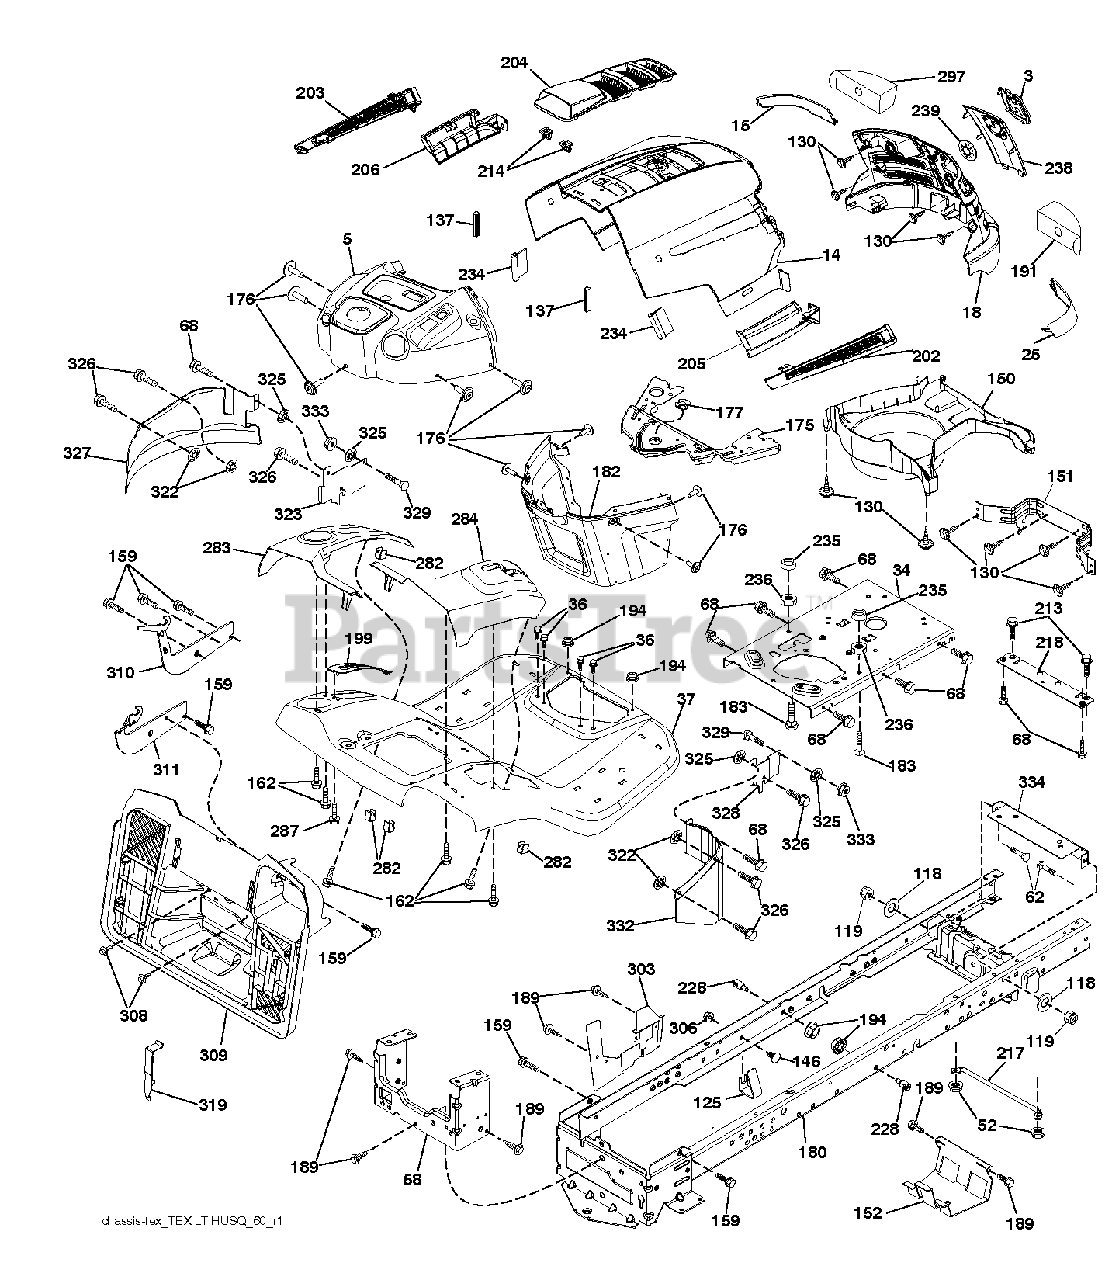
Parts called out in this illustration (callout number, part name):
3	LOGO.HUSQ.GT.LT.CROWN.H
5	SUBASM.DASH.UPPER.W/BUMPER
14	HOOD.HUSQVARNA.LT.ORANGE
15	LENS.HUSQVARNA LT.RH
18	GRILLE.SVC.HUSQVARNA.GREY
25	LENS.HUSQVARNA LT.RH
34	PLATE.ENGINE.10GA.CRD.GENII
36	SCREW 5/16"
52	LOCKNUT
58	DRAWBAR UPPER 2PC SMALL FENDER
62	BOLT D
68	SCREW LT
118	WASHER
125	CLIP.FUEL.LINE
130	SCREW.#10 X 0.750.BOS
137	BUMPER DASH
146	BOLT.RDHD.SHT.SQNK.3/8-16X5/8
151	BRACKET PIVOT
152	SHIELD.BROWNING.W/TEX
159	SCREW, 3/8-16X3/4
162	SCREW.HI-LO.CONSOLE
175	CROSSMEMBER
176	SCREW.#10-24X5/8.RN.QU
177	BUSHING STEERING
180	CHASSIS.WLDMNT.14GA.2PC.18".TI
182	DASH.LOWER.PREDATOR LT
183	BOLT.5/16-18X1-1/4 FULL THD
189	SCREW
191	INSERT.REFLECTIVE.RH.
194	NUT LOCK HEX FLANGE 5/16-18
199	PLATE DECK LIFT
202	VENT.SIDE.HUSQVARNA.LT.RT
203	VENT.SIDE.HUSQVARNA.LT.LFT
204	SUBASM.TOP.VENT.HUSQ.LT
205	SKIRT.SIDE.HUSQVARNA.LT.RT
206	SKIRT.SIDE.HUSQVARNA.LT.LEFT
213	BOLT
214	CLIP.RETAINER.TINNER.
217	ROD.PIVOT.HOOD
218	X-PIECE.HOOD.STOP.NON/
228	STUD.FASTNER.W/ANTI-ROTATE
234	BUMPER.HOOD.TEX.HUSQVARNA
235	SPACER FENDER
236	NUT.CENTERLOCK.5/16-
238	TRIM.HUSQ LT.668
282	CLIP.RETAINER.CONSOLE.LT.HUSQ
283	CONSL.DECKLIFT.LH.SRD.TEX.CRD
284	CONSL.SHIFT.GEAR.RH.SRD.GREY
287	SCREW 1/4X20
297	INSERT REFLECTIVE
303	SHIELD CHASSIS LEFT
306	NUT LOCK FLG 3/8-16 UNC
308	BOLT, 5/16-18 X 1 3/4
309	BACKPLATE.BAGGER.V2.SRD
310	LH.ADJUST.HANGER.BRACKET.ASM
311	RH.ADJUST.HANGER.BRACKET.ASM
319	BRACKET.ACTUATOR.BAGGER.SRD
322	PALNUT 1/4
323	GUARD FRONT LEFT
325	WASHER 5/16"
326	SCREW 14-20 X 5/8
327	GUARD LEFT
328	GUARD FRONT RIGHT
329	BOLT
332	GUARD RIGHT
333	NUT.71038.31-18.HEX.NYLOCK
334	BRACKET.ENGINE
